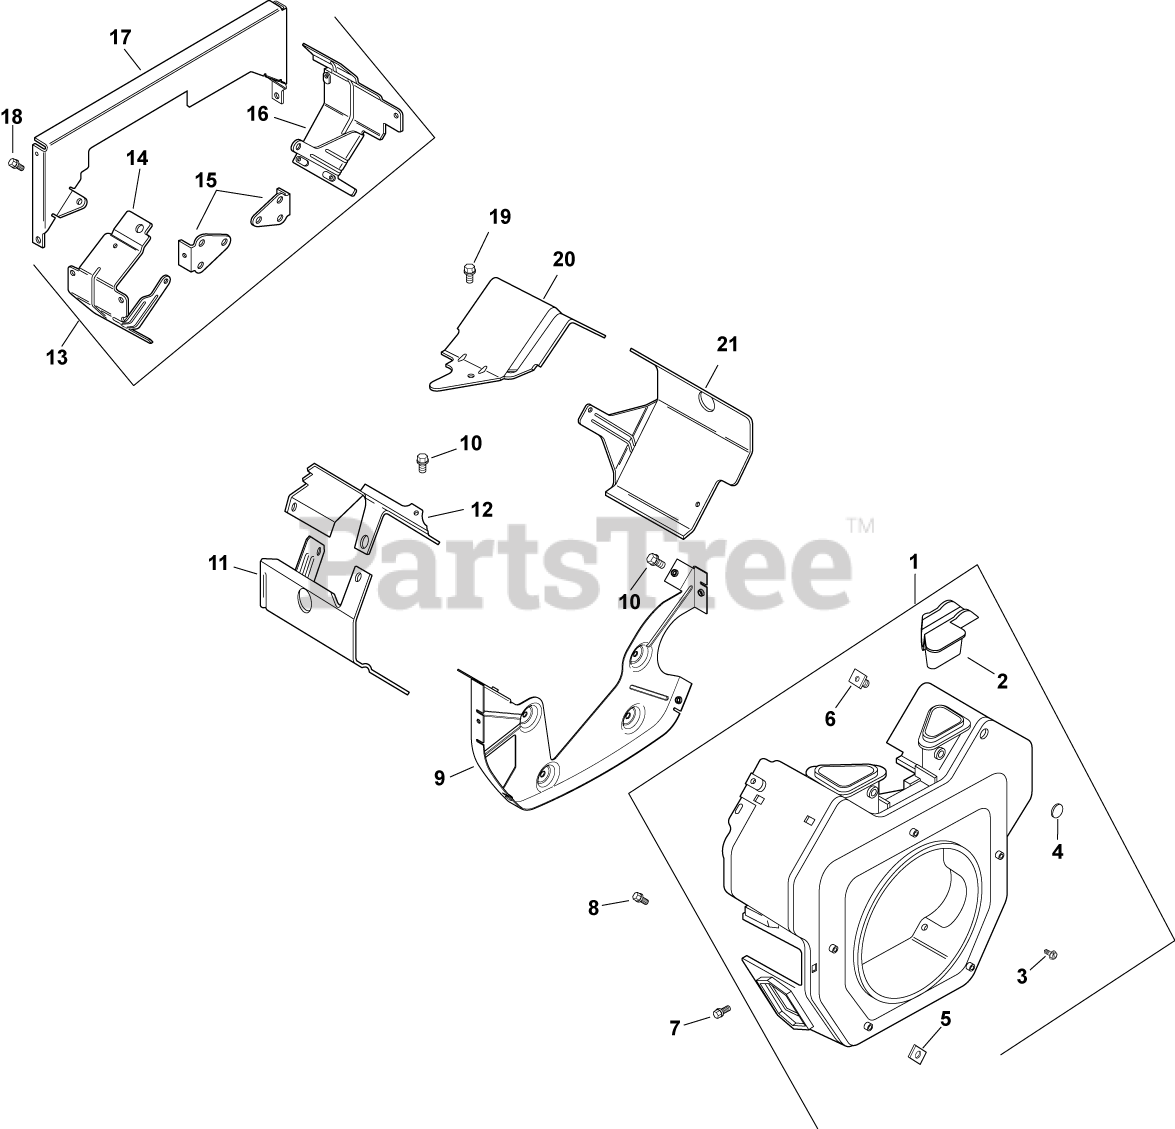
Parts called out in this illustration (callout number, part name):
1	KIT, BLOWER HOUSING ASSEMBLY - USE 24 027 491-S
2	COVER, BLOWER HOUSING-USE 24 096 119-S
3	SCREW, WSH HD TAP #8-18X1/2"
4	PLUG, BUTTON 9/16
5	NUT, PLASTIC (KM)-USE 25 100 37-S
6	NUT, PLASTIC
7	SCREW - USE M-545016-S
8	SCREW, FLG THD FRM M5X.8X20-(#25086399S)
9	PLATE, BACKING-USE 24 146 59-S
10	SCREW,FLG THD FRM M6X1.0X16-(#25086397S)
11	KIT, CYL BAFFEL #2 SIDE
12	BAFFLE, VALLEY #2 SIDE-USE 24 063 94-S
13	KIT, "Q"DUCT"
14	BAFFLE, DUCTED AIR-OIL FILTER
16	BAFFLE, DUCTED AIR-STARTER
17	PLATE, BACKING
18	SCREW, FLG M6X1.0X10
19	SCREW, FLG THD FRM M5X.8X10
20	BAFFLE, VALLEY (CH)-USE 24 063 93-S
21	KIT, CYL BAFFEL #1 SIDE
4103710-S	NAMEPLATE, SERVICE
25086158-S	SCREW, FLNG THD FRM M6X1.0X10 USE 25 086 406-S
